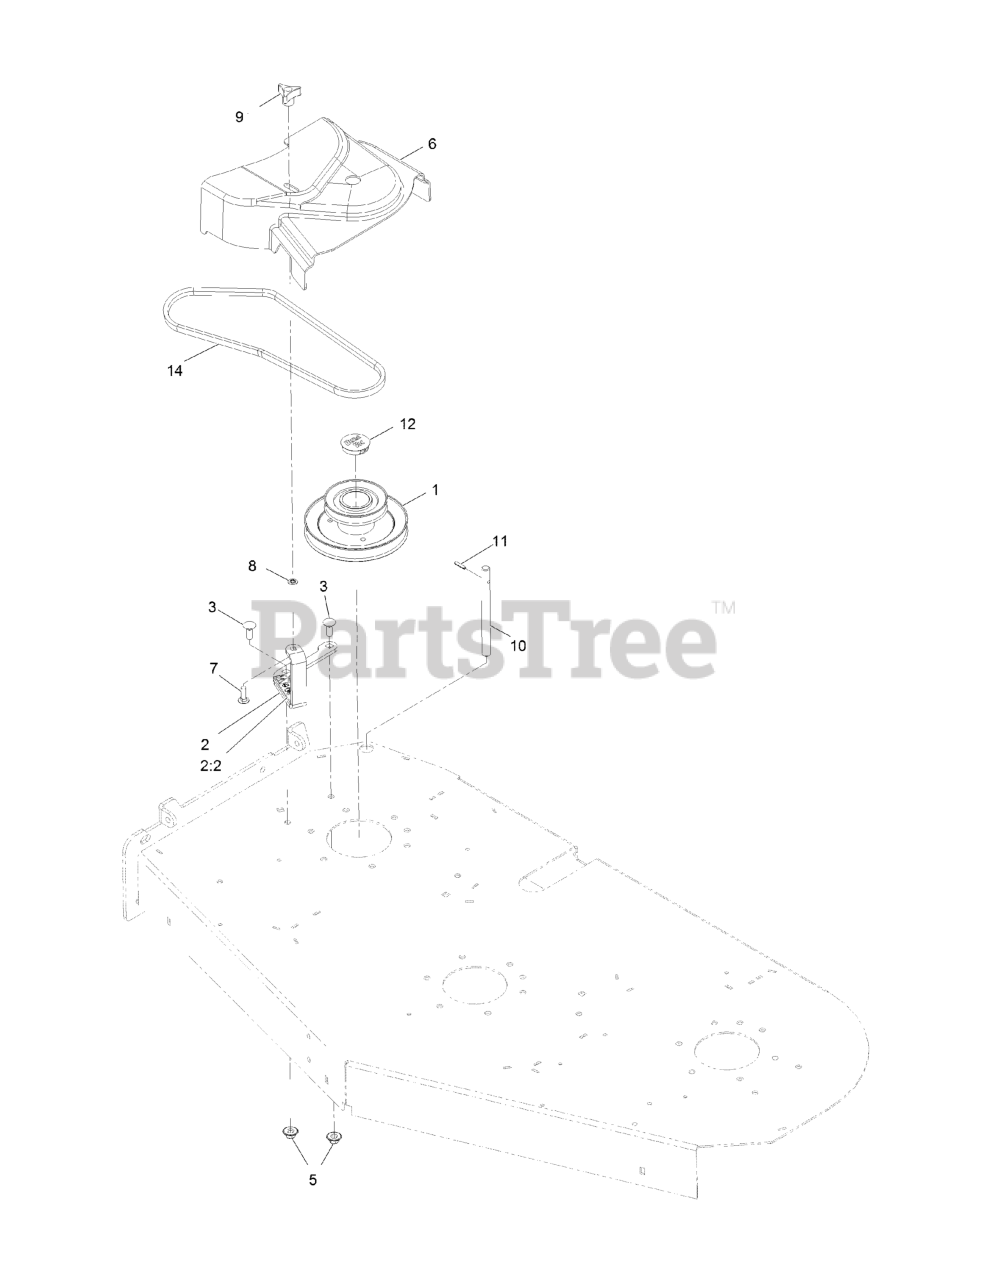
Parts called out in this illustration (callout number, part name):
1	JACKSHAFT-UV DRIVE 523
2	ASM-CVR BRKT W/DECAL
2:2	DECAL-DANGER
3	BOLT-CARR
5	Nut-Nyloc 3/8-16 Flg
6	COVER-BELT, UV 52
7	BOLT-CARR
8	RING-RETAINING, BOLT
9	KNOB-3 PRONG
10	SHAFT-CATCHER, GRASS
11	PIN-ROLL
12	PLUG, BLACK NYLON 1.75
